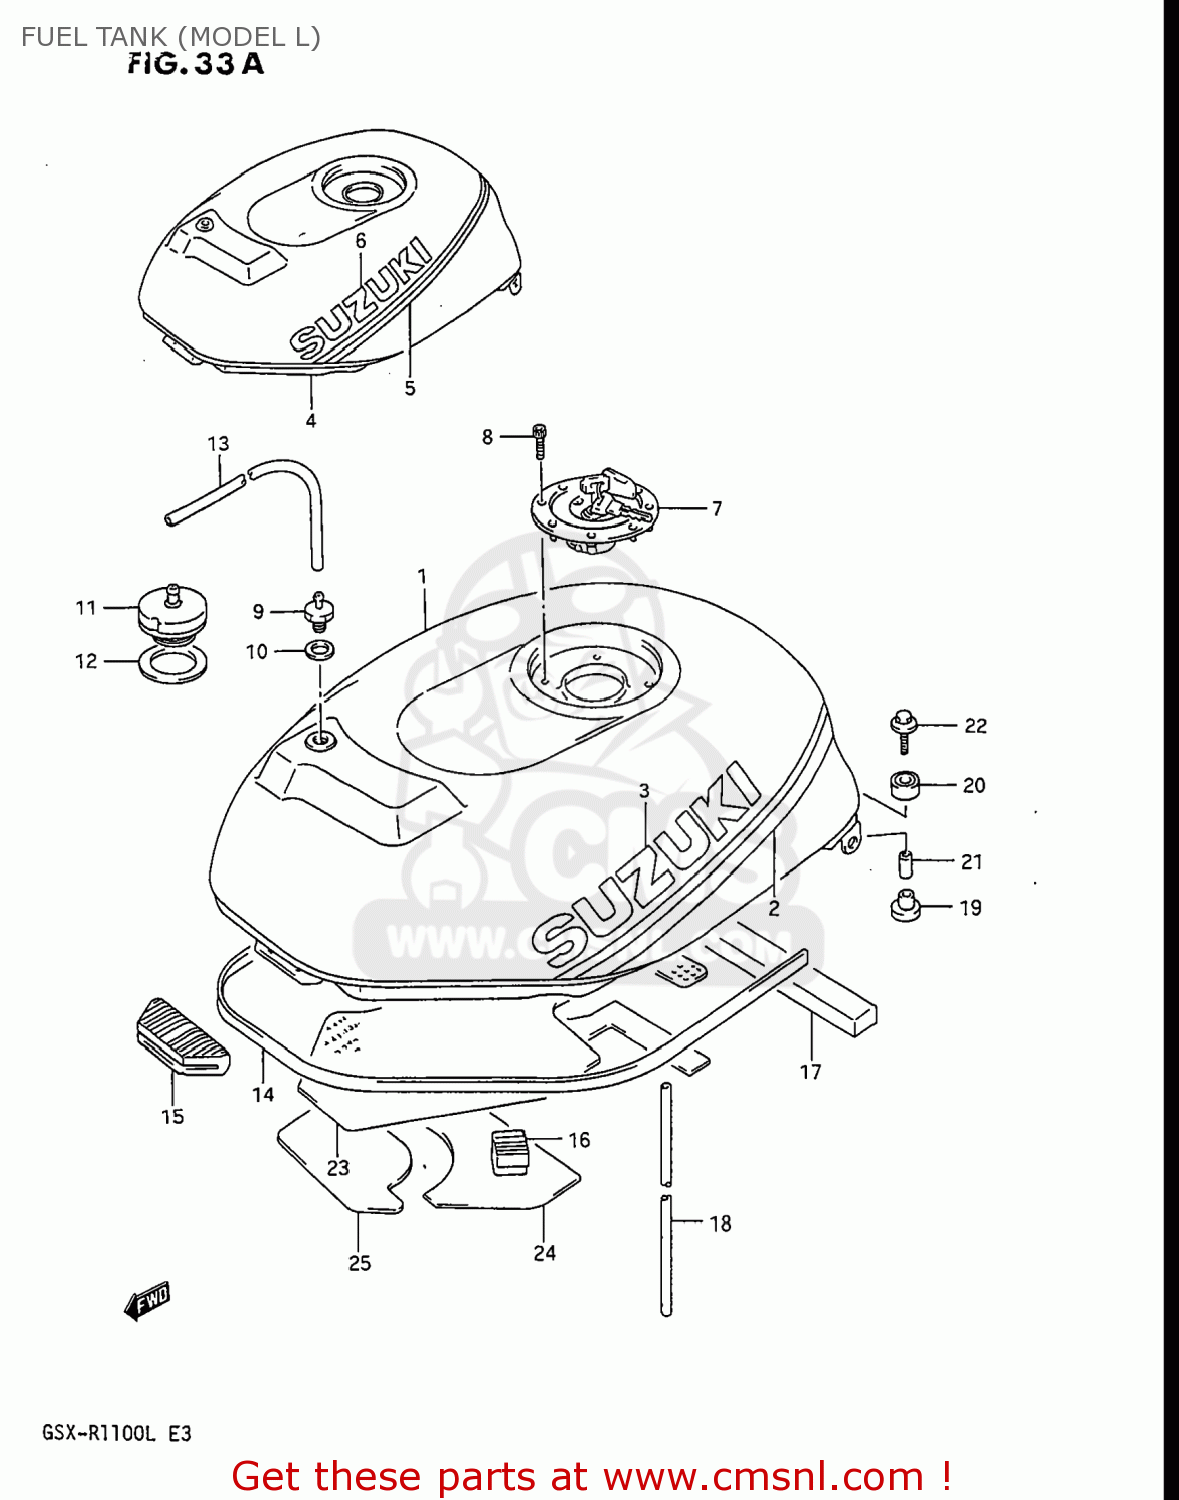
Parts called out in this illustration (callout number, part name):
1	TANK ASSEMBLY,FUEL
2	TAPE,FUEL TANK STRIPE
3	EMBLEM,FUEL TANK
4	TANK ASSEMBLY,FUEL
5	TAPE,FUEL TANK
6	EMBLEM,FUEL TANK
7	CAP SET,FUEL TANK
8	BOLT(5X20)
9	PLUG,FUEL TANK BREATHER
10	GASKET(12.5X20X2.5) (NAS)
11	(CA) VALVE,FUEL TANK BREATHER
12	GASKET 27X40X2.5 (NAS)
13	HOSE(5X8.2X600)
14	MOLDING,FUEL TANK
15	CUSHION,FUEL TANK FR
16	CUSHION,TANK,S
17	CUSHION, AIR SEAL
18	HOSE
19	CUSHION
20	CUSHION
21	SPACER
22	BOLT(6X35)
23	HEAT SHIELD,FUEL TANK
24	HEAT SHIELD,FUEL TANK IN
25	HEAT SHIELD,FUEL TANK IN
